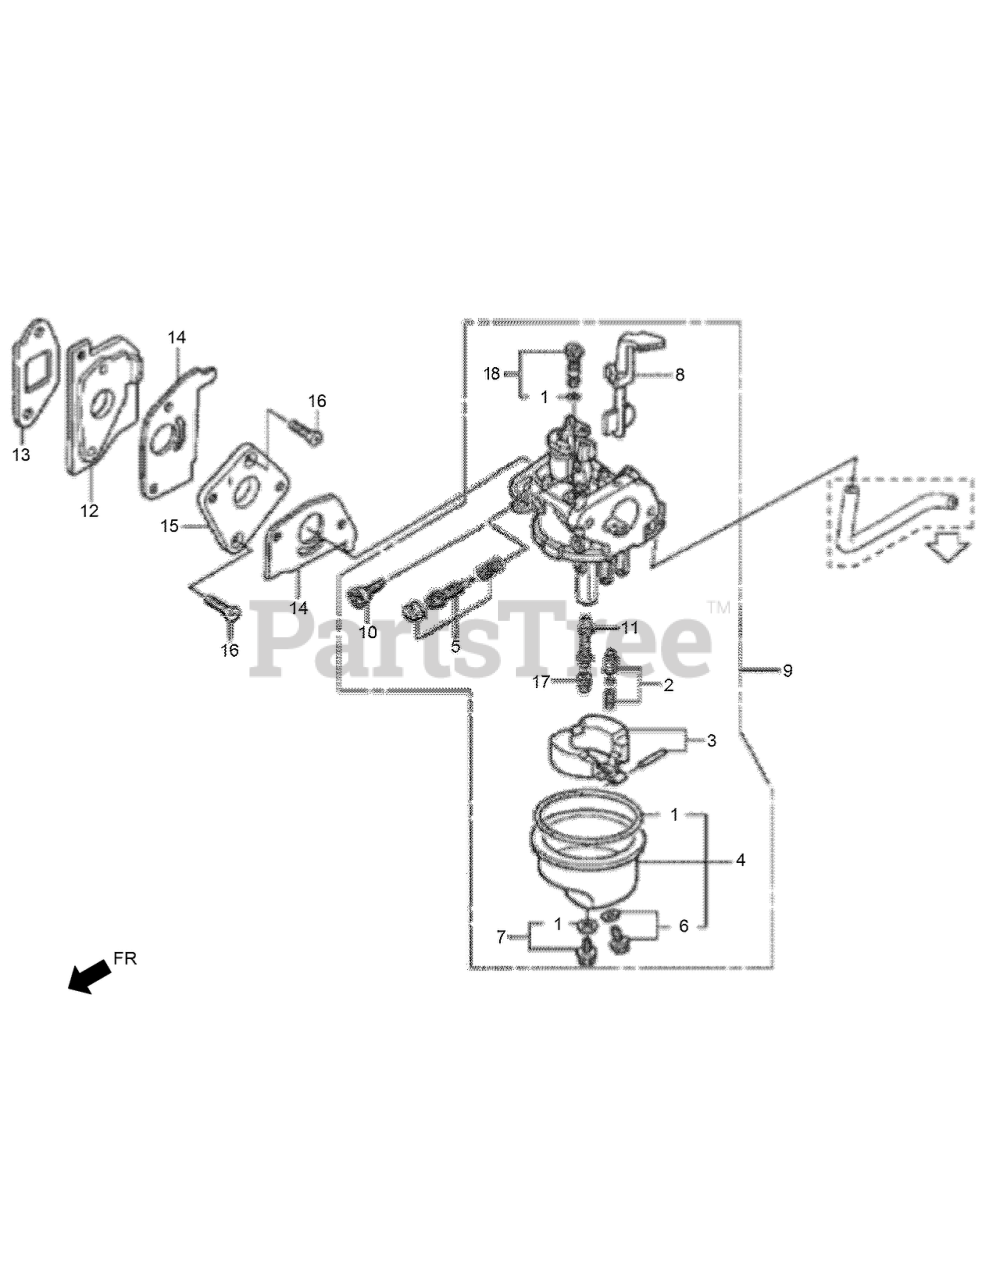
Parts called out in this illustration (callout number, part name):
1	GASKET SET
2	VALVE SET-FLOAT
3	FLOAT SET
4	CHAMBER SET-FLOAT
5	SCREW SET-PILOT
6	SCREW SET-DRAIN
7	SCREW SET
8	CHOKE SET
9	CARBURETOR ASM
10	SCREW-THROTTLE STOP
11	NOZZLE-MAIN
12	INSULATOR-CARBURETOR
13	PACKING-INSULATOR
14	PACKING-CARBURETOR
15	PLATE-CARBURETOR JOINT
16	SCREW-FLAT-5X20
17	JET-MAIN NO. 52
18	JET SET-PILOT, NO. 35
